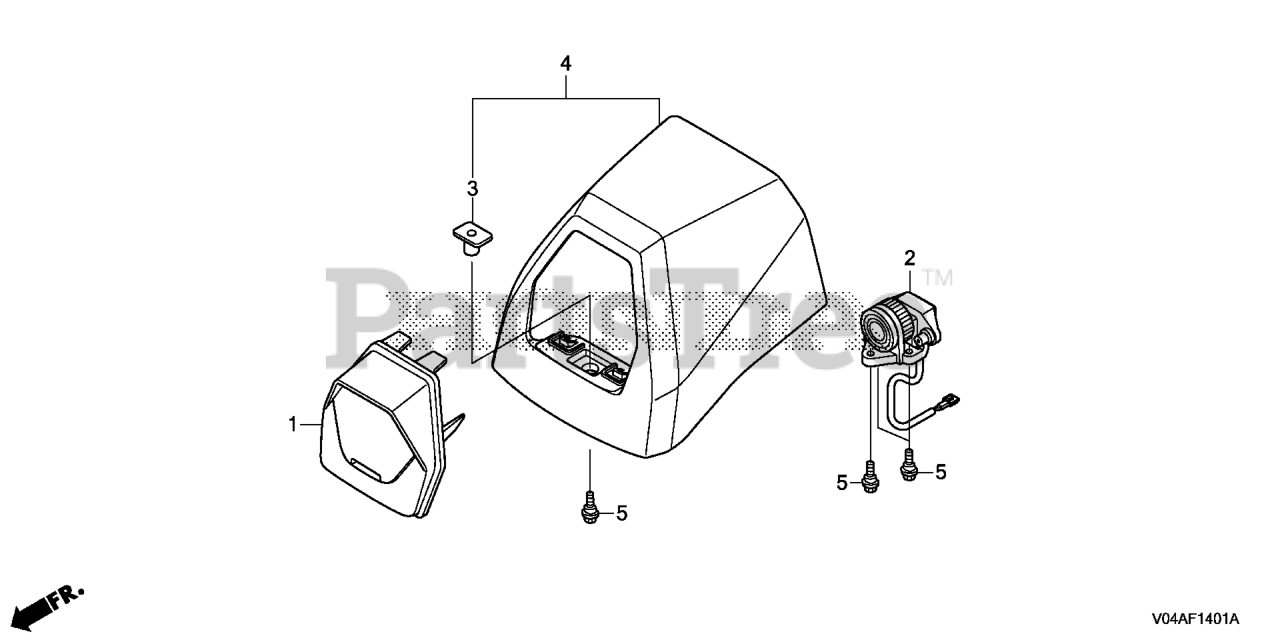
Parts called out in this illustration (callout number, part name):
1	LENS, HEADLIGHT *TCLEAR* (CLEAR)
2	HEADLIGHT ASSY.
3	NUT, SPECIAL (6X7)
4	COVER, HEADLIGHT *NH296* (ALPS GRAY)
5	BOLT, FLANGE (6MM)
